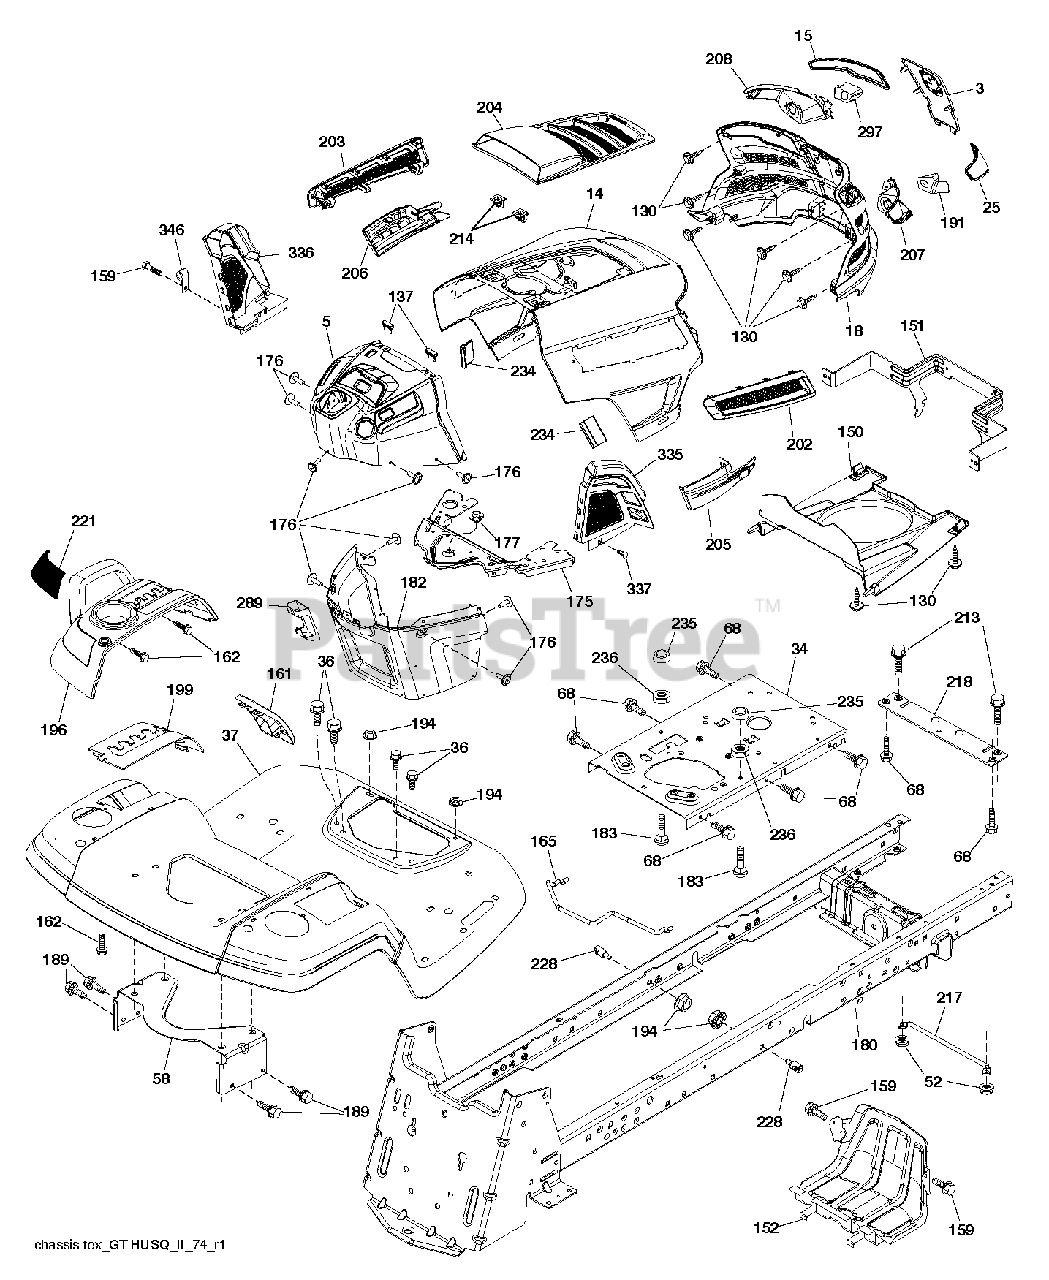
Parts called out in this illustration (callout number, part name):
3	APPLIQUE.SUBASM.GT.HUSQ.II
5	DASH.UPP.GT2.SM.PTO.MCHOKE
14	HOOD.ASM.HUSQVARNA.GT.TEX.ORAN
15	LENS.HEADLIGHT.LH.GTII.2011
18	GRILLE.SUBASM.GT.HUSQ.II
25	LENS.HEADLIGHT.RH.GTII.2011
34	PLATE.ENGINE.WELDED.CHASSIS
36	SCREW 5/16"
37	FENDER.PNT.TX.GT.CH/FW/DL.HUSQ
52	LOCKNUT
58	BRKT.SUPPORT.FNDR/TANK
68	SCREW LT
130	SCREW.#10 X 0.750.BOS
137	BUMPER DASH
150	AIR.DUCT.GTV.BLACK
151	BRACKET.PIVOT.HOOD.GT.HUSQ.II
152	SHIELD.BROWNING.PNT.GT.V2
159	SCREW, 3/8-16X3/4
161	CONSOLE.WINDOW.FUEL.HUSQ.GT
162	SCREW.HI-LO.CONSOLE
165	SUPPORT.TANK.REAR.W/TEX
175	PLATE.CROSSMEMBER.HUSQ
176	SCREW.#10-24X5/8.RN.QU
177	BUSHING, STEERING
180	CHASSIS.GT.SLOPED.DRAWBAR.
182	DASH.LOWER.COMMON.12V.ADAPTOR
183	BOLT.5/16-18X1-1/4 FULL THD
189	SCREW
191	INSERT.REFLECTIVE.RH.HUSQ.GTII
194	NUT LOCK HEX FLANGE 5/16-18
196	SUBASM.CONSOLE.HUSQ.GT.DECKLFT
199	PLATE.DECK.LIFT.HUSQVARNA.GT
202	VENT.SIDE.RH.GT.HUSQ.II.
203	VENT.SIDE.LH.GT.HUSQ.II.498
204	VENT.TOP.HUSQ.GT2
205	SIDE.TRIM.RH.GT.HUSQ.II
206	SIDE.TRIM.LH.GT.HUSQ.II.GRAY
207	BEZEL LIGHT.RH.GT.II.MYLAR
208	BEZEL LIGHT.LH.GT.II.MYLAR
213	BOLT
214	CLIP.RETAINER.TINNER.
217	ROD.PIVOT.HOOD
218	X-PIECE.HOOD.STOP.NON/
221	REFLECTOR.LH.TEX GT HU
228	STUD.FASTNER.W/ANTI-ROTATE
234	BUMPER.HOOD.TEX.HUSQVARNA
235	SPACER FENDER
236	NUT.CENTERLOCK.5/16-
289	PLUG.N/CRUISE.COMMON.YT/GT.BLK
297	INSERT.REFLECTIVE.LH.HUSQ.GTII
335	COVER.RH.CLOSE.OUT.BLACK
336	COVER-LH.LOWER.DASH.GT2.BLACK
337	CLIP.XMAS.TREE.ITW.2622-00
346	CLIP,INSULATOR
